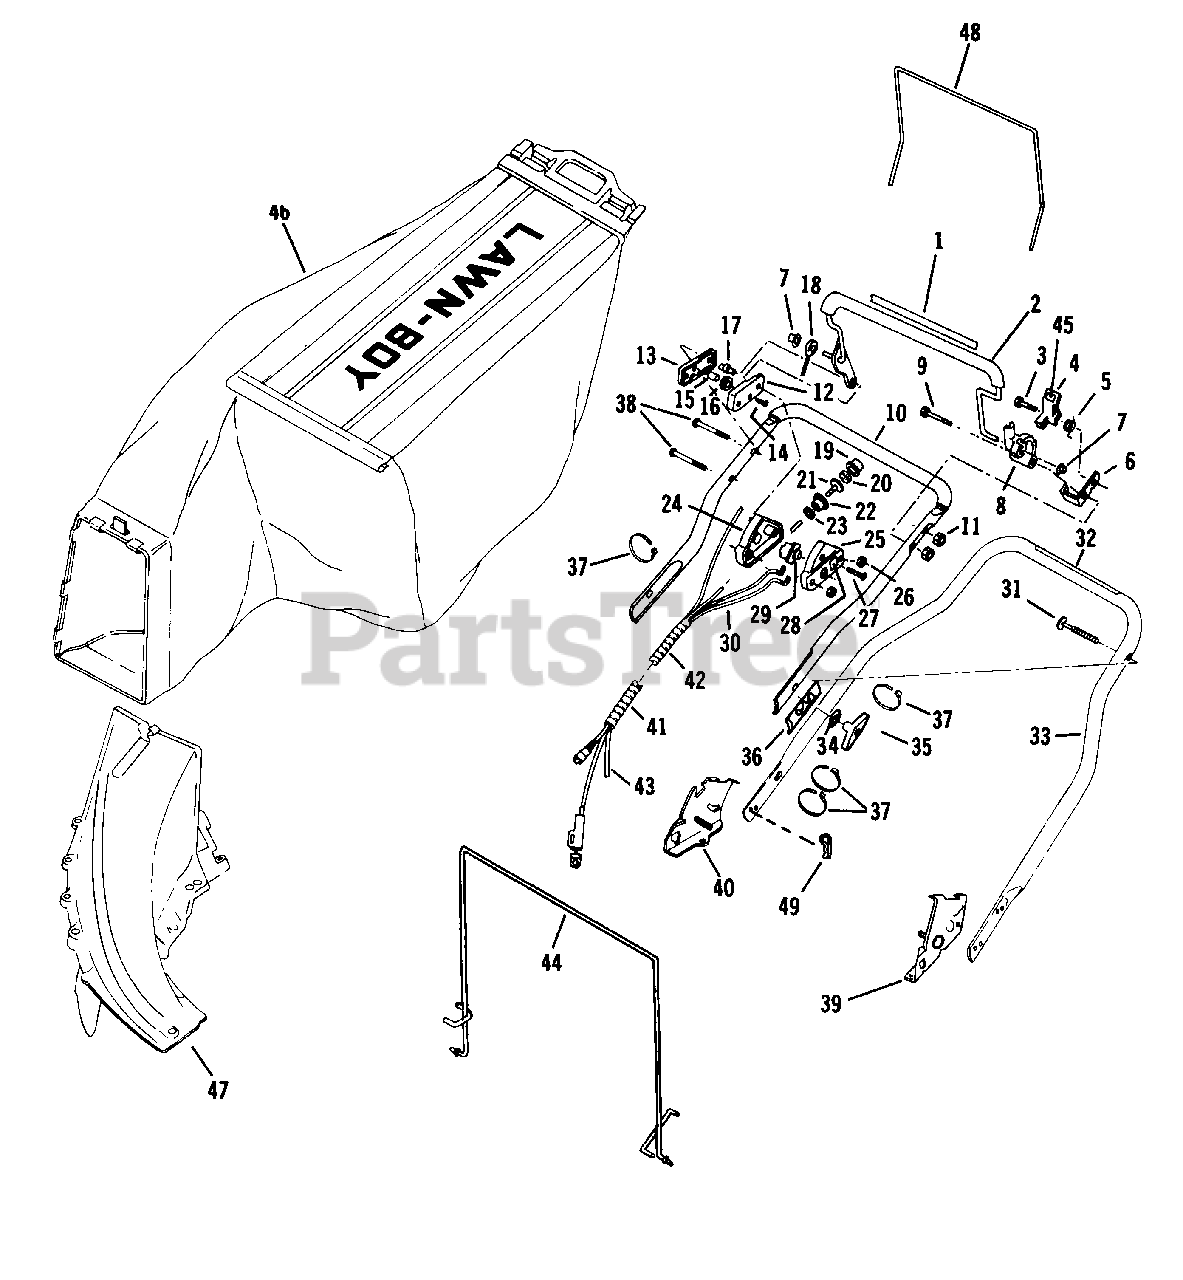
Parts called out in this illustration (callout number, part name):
1	Decal-Blade Control
2	Control Lever Assembly
3	Shoulder Bolt-Latch Lever Mounting
4	Stop-Latch Lever
5	Spring-Torsion
6	Bracket-Bail Stop
7	Push Nut
8	Cam-Clutch Control
9	Shoulder Bolt-Cam Mounting
10	Top Handle and Grip Assembly
11	Lock Nut
12	Control Case-Inner
13	Control Case-Outer
14	Screw-Truss Head
16	Pulley
18	Control Cable Assembly
19	Primer Bulb
21	Primer Base
23	Locknut
24	Console Right
25	Console Left
26	Locknut-Hex
27	Screw-Truss Head
28	Decal-"OFF-ON"
29	Switch Assembly
30	Wire Harness Assembly
31	Screw-Folding Handle
32	Decal-Starting Inst.
33	Handle-Bottom
35	Knob-Folding Handle
36	Bracket-Rear Hanger
37	Tie Strap
39	Handle Bracket-L.H.
40	Handle Bracket-R.H.
41	Spiral Tubing
42	Spiral Tubing
43	Tubing-Primer
44	Hanger Assembly-Front
45	Decal-Latch Lever
46	Bag Assembly
47	Chute Assembly
48	Hanger-Rear
49	Hair Pin
